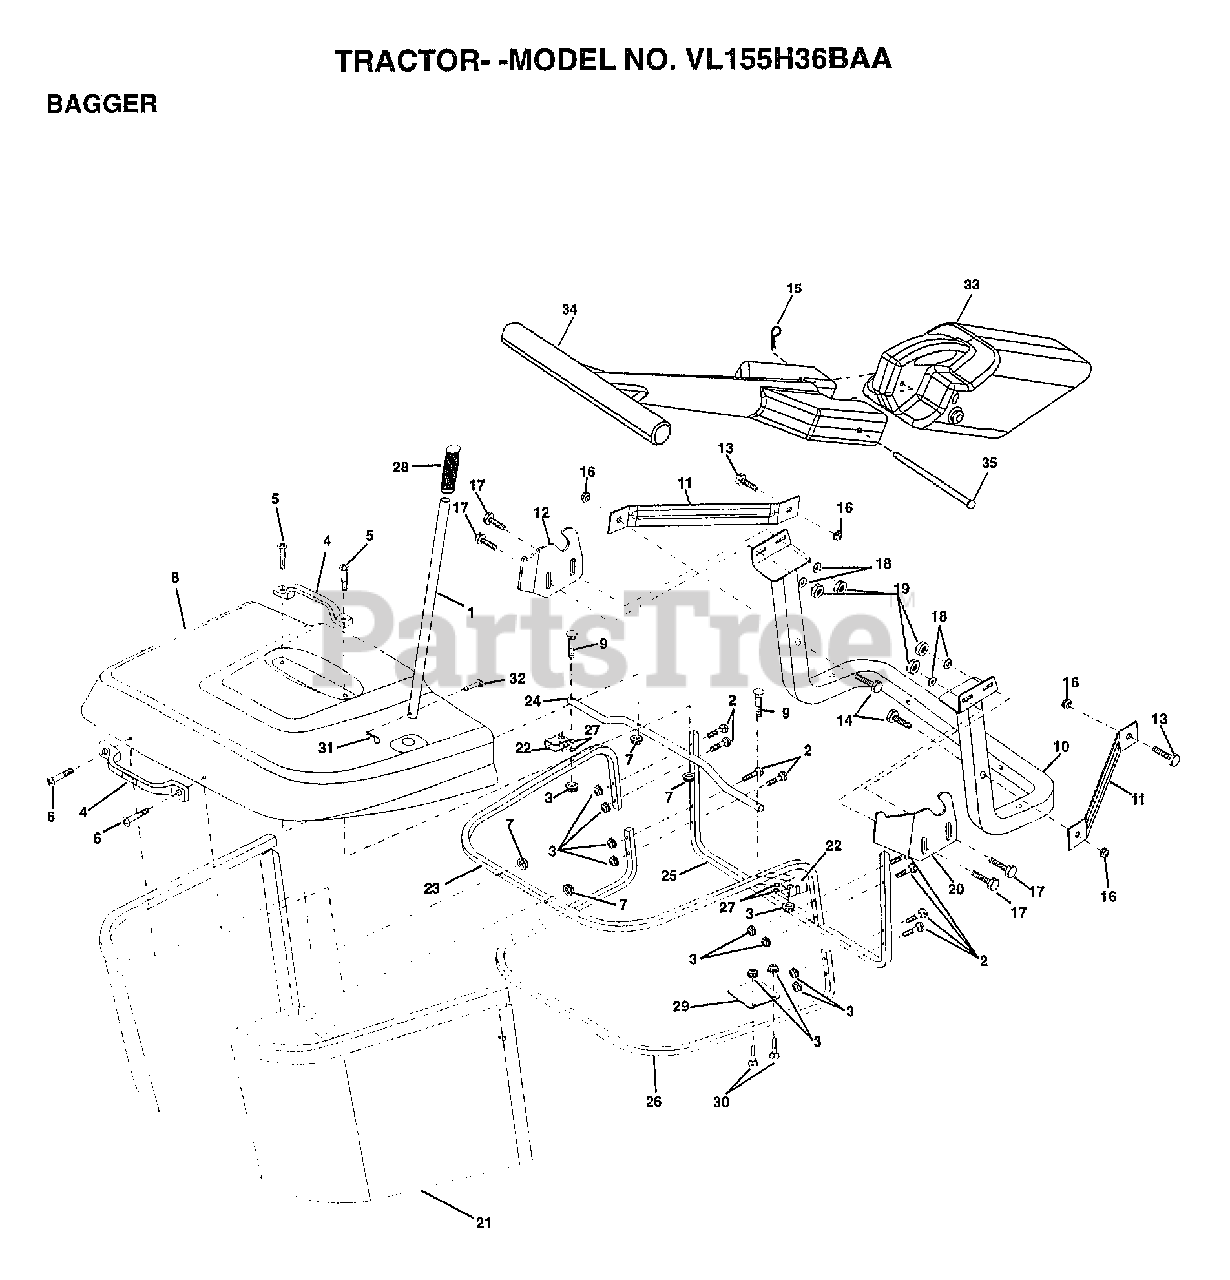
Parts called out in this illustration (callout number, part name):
1	TUBE.HDLE.BAG.CRD
2	BOLT.CARRIAGE.1/4-20X2.0
4	HANDLE.GRAB.BLACK.
5	"SCREW,PAN.HEAD"
8	COVER.BAGGER.CRD
9	BOLT CARRIAGE
10	SUPT.ASM.WLDMNT.BAG.CRD
11	BRKT.SUPT.UPPER.BAG.CRD
12	BRKT.PIVOT.BAG.LH.CRD
13	BOLT
14	BOLT.HEX.3/8-16X2-1/2
17	BOLT
18	WASHER
19	NUT
20	"BRKT.PIVOT.BAG,RH.CRD"
21	BAG.ASM.CRD
22	BRKT.SIDE.BAG.CRD
23	TUBE.UPPER.BAG.CRD
24	TUBE.PIVOT.BAG.CRD
25	TUBE.FT.BAG.CRD
26	TUBE.LOWER.BAG.CRD.
27	GROMMET.EXTRUDED
28	GRIP.HANDLE.BLACK
29	PLATE.STOP.BAG.HDLE.CRD
30	BOLT.CARRIAGE
31	RETAINER M
32	RIVET.DRILL.1.75
33	PLUG.MULCHER.92 CRD
34	HANDLE.MULCHER.92.CRD
35	PIN.MULCHER.92 CRD
